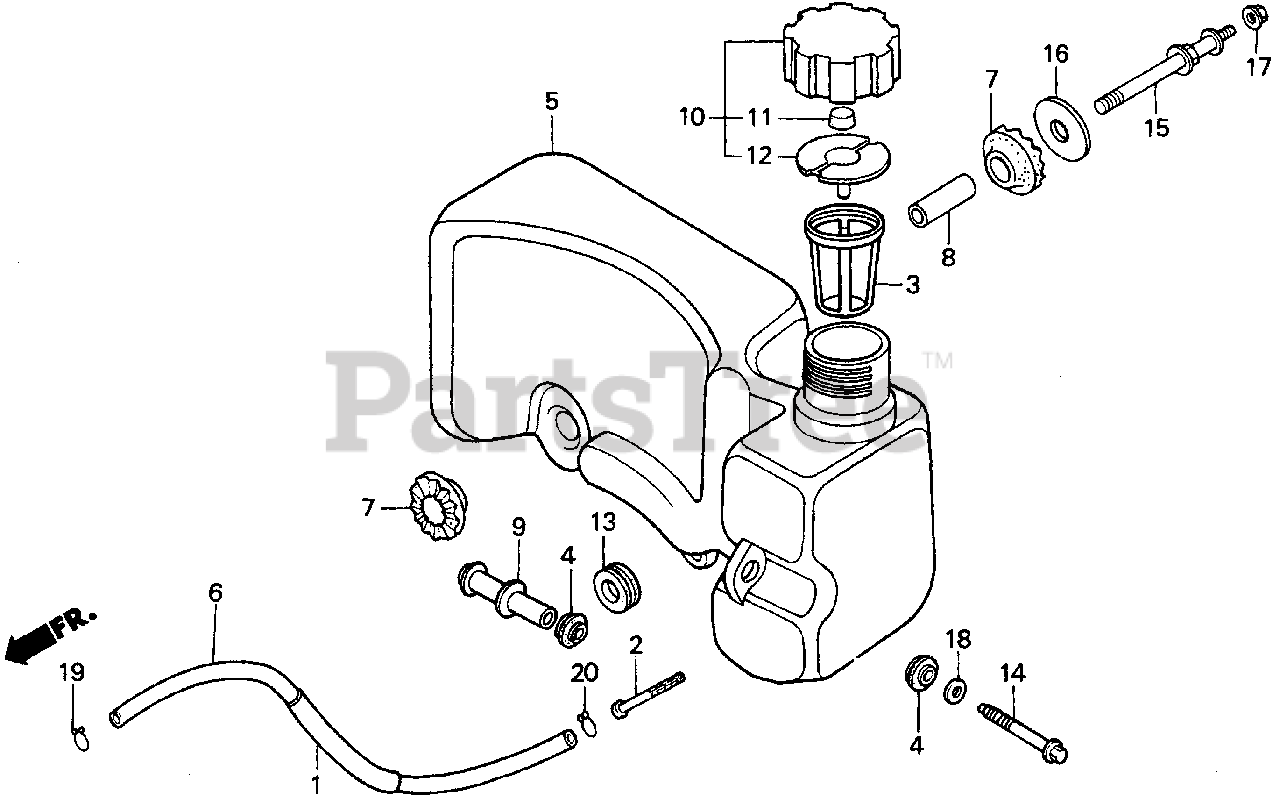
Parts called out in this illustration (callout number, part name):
1	RUBBER, SUPPORTER (107MM)
2	FILTER, FUEL
3	GAUGE, FUEL LEVEL (NOT AVAILABLE)
4	RUBBER, TANK SETTING
5	TANK, FUEL
6	TUBE, FUEL
7	RUBBER B, TANK MOUNTING
8	COLLAR, TANK SETTING
9	COLLAR, TANK
10	CAP ASSY., FUEL TANK
11	SPONGE, FUEL CAP BREATHER
12	GASKET, FUEL CAP
13	CUSHION, RR. FENDER
14	BOLT, FLANGE (6X50)
15	BOLT, TANK STAY
16	WASHER, TANK MOUNTING
17	NUT, FLANGE (6MM)
18	WASHER, PLAIN (6MM)
19	CLIP, TUBE (B8)
20	CLIP, TUBE (C11)
